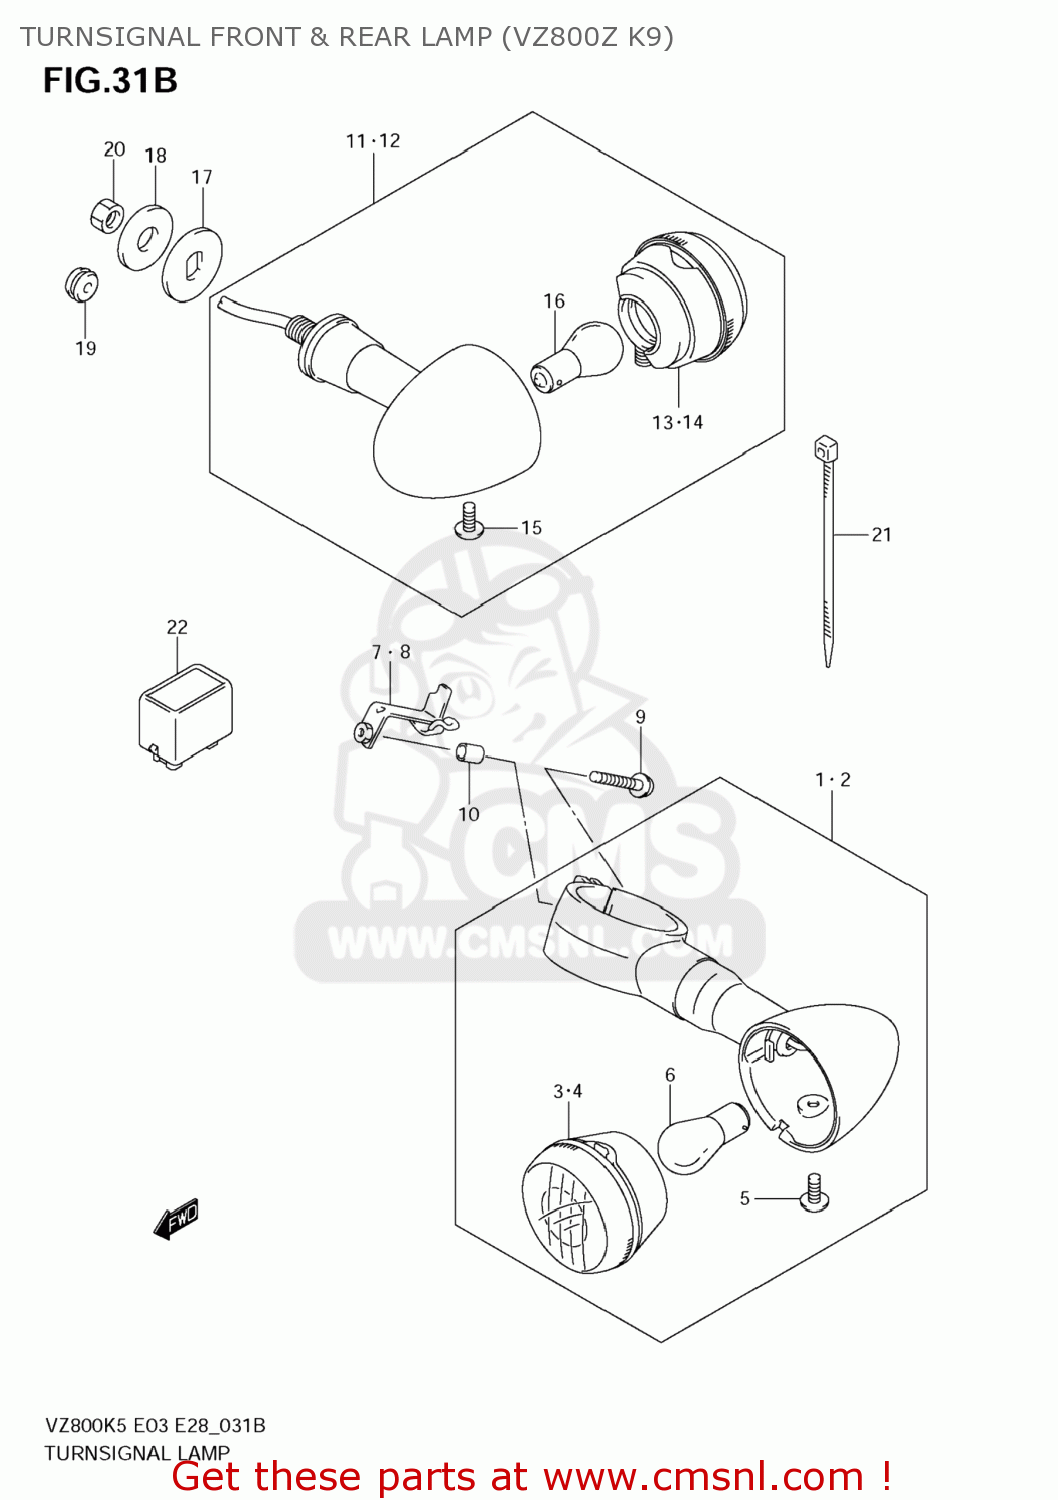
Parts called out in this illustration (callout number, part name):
1	LAMP ASSY,FR TURN SIGNAL,R
2	LAMP ASSY,FR TURN SIGNAL,L
3	LENS
4	LENS
5	SCREW(4X10)
6	BULB(12V23/8W)
7	BRACKET,FR TURNSIGNAL,R
8	BRACKET,FR TURNSIGNAL,L
9	SCREW(6X25)
10	SPACER(6.4X9.2X12)
11	LAMP ASSY,RR TURNSIGNAL,R
12	LAMP ASSY,RR TURNSIGNAL,L
13	LENS
14	LENS
15	SCREW(4X10)
16	BULB(12V21W,AMBER)
17	SPACER,RR TURNSIGNAL
18	WASHER(10.5X30X2.3)
19	GROMMET
20	NUT
21	CLAMP(L:145)
22	RELAY ASSY,TURNSIGNAL LAMP
